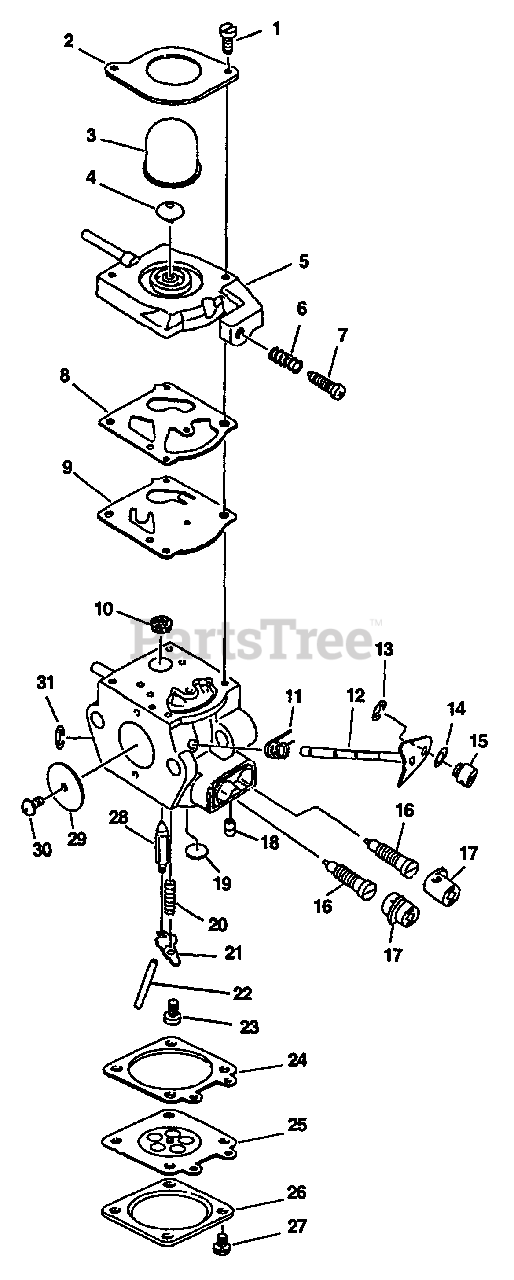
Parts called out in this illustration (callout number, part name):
1	SCREW, PUMP COVER
2	RETAINER, PURGE BULB
3	BULB, PURGE
4	VALVE, CHECK
5	BASE, PURGE
6	SPRING, IDLE ADJUST
7	SCREW, IDLE ADJUST
8	GASKET, PURGE
9	DIAPHRAGM, PURGE
10	STRAINER
11	SPRING, THROTTLE RETURN
12	SHAFT, THROTTLE
13	RING, RETAINING
16	NEEDLE - MIXTURE
17	CAP, LIMITER
18	NOZZLE, CHECK VALVE
19	PLUG, WELCH
20	SPRING, METERING LEVER
21	LEVER, METERING
22	PIN, METERING LEVER
23	SCREW, METERING LEVER PIN
24	GASKET, METERING
25	DIAPHRAGM, METERING
26	COVER, METERING
27	SCREW
28	VALVE, INLET NEEDLE
29	VALVE, THROTTLE
31	RING, RETAINING
